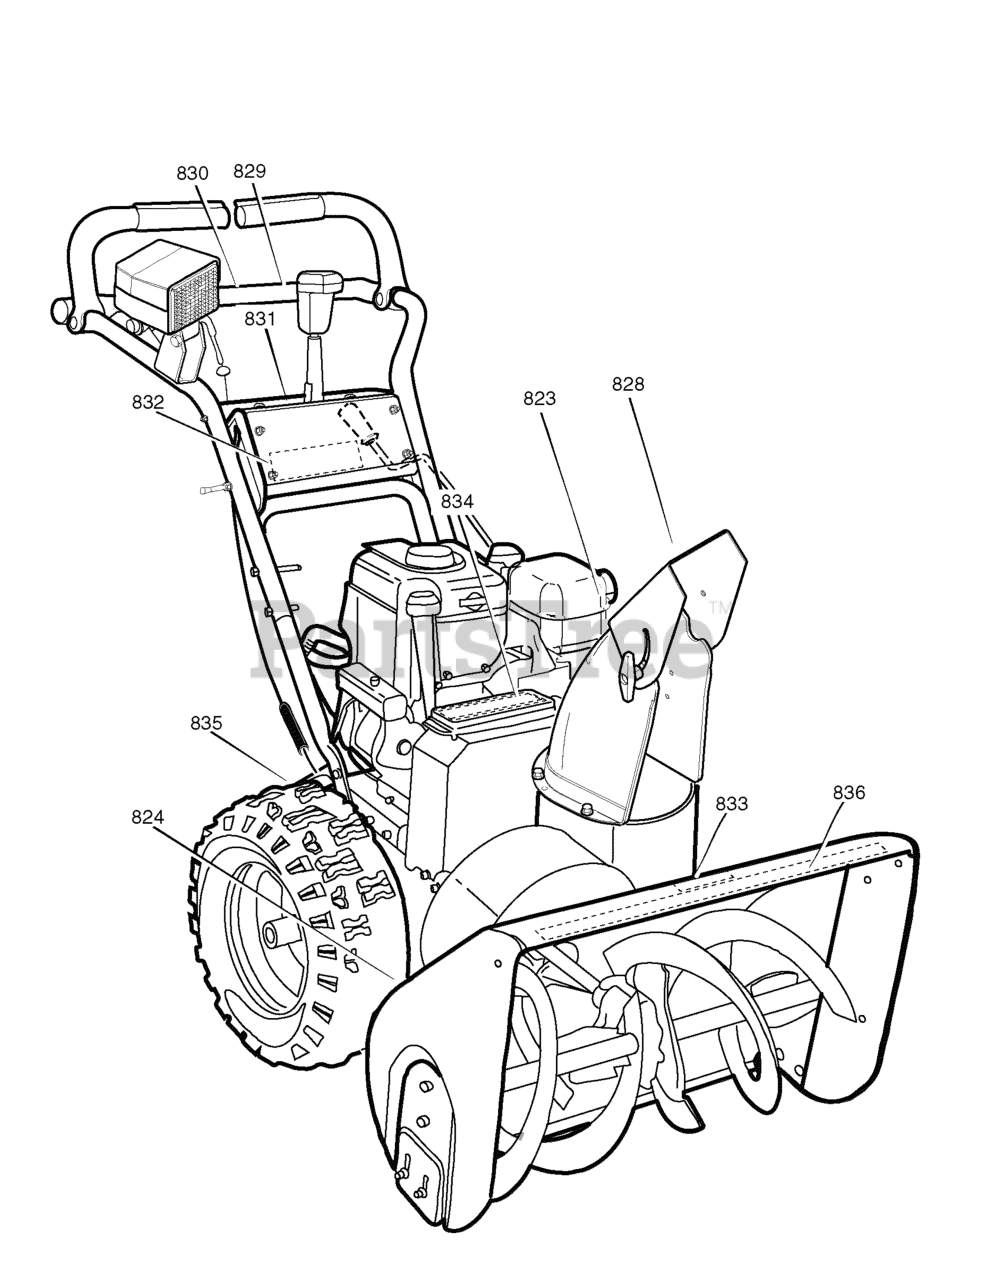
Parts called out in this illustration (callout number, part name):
823	DECAL, DANGER CHUTE HAND
824	DECAL, DANGER FOOT
828	DECAL, THROWN OBJECTS
829	DECAL, DRIVE CLUTCH
830	DECAL, AUGER CLUTCH
831	DECAL, GEAR SELECTOR
832	DECAL, CRAFTSMAN
833	DECAL, CLEAN & CLEAR BRUSH
834	DECAL, TOOLBOX INFORMATION
835	DECAL, ID PLATE
836	DECAL, 1550/30 CRAFTSMAN AUGER
